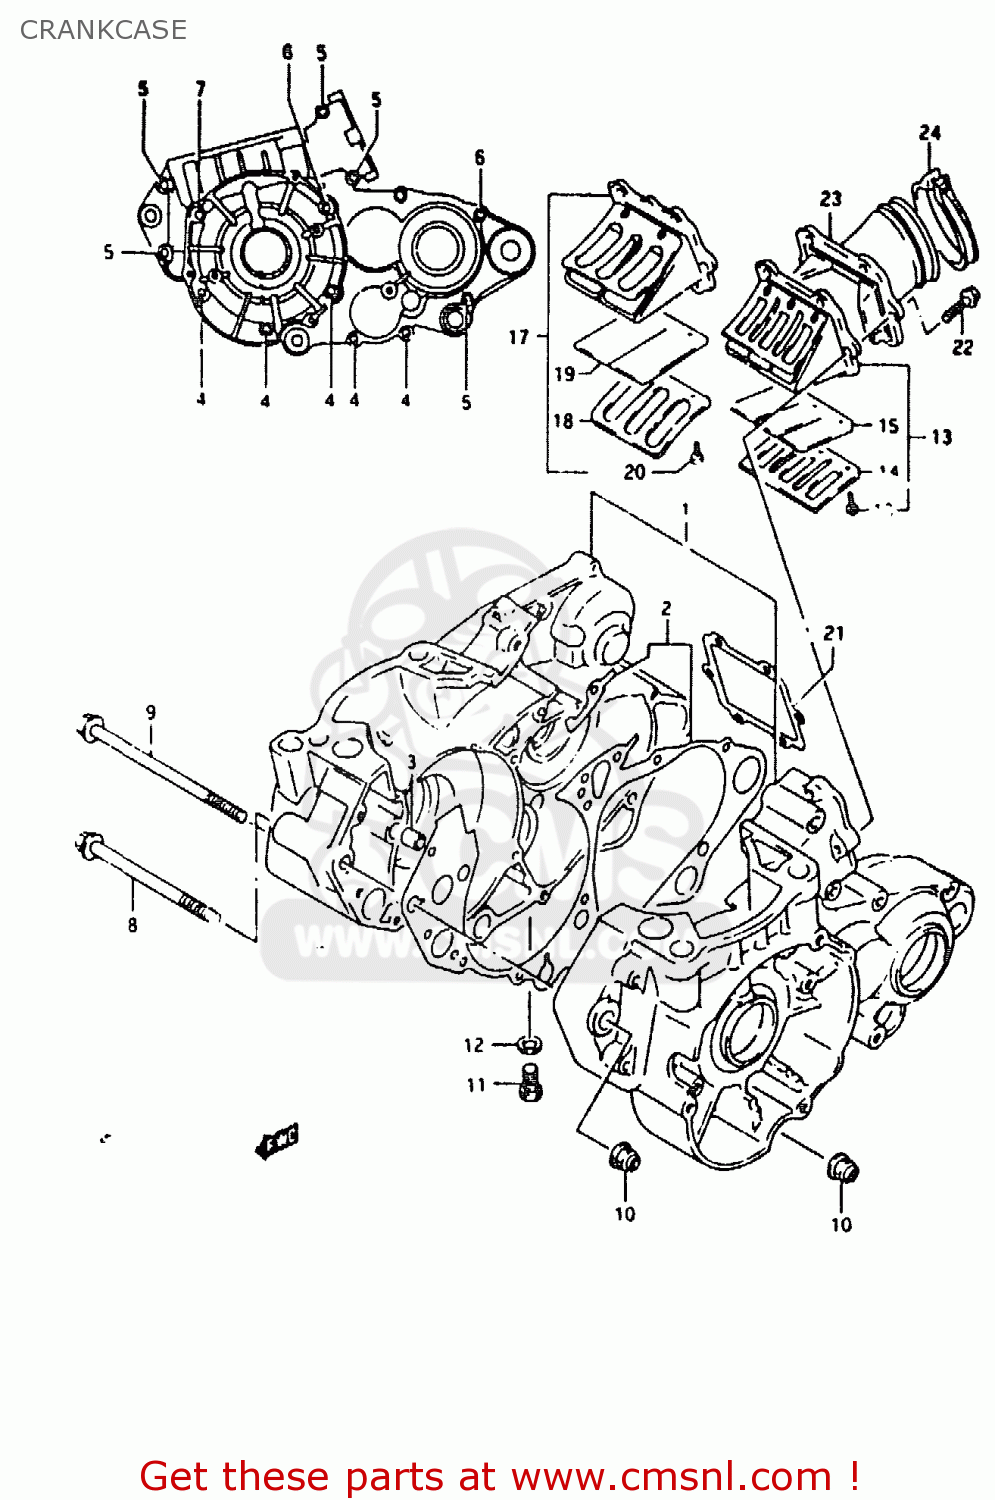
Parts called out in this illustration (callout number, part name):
1	CRANKCASE SET
2	GASKET,CRANKCASE (NAS)
3	PIN
4	BOLT
5	BOLT
6	BOLT
7	BOLT
8	BOLT
9	BOLT
10	NUT
11	BOLT
12	GASKET(8.2X14X1) (NAS)
13	VALVE ASSEMBLY,REED
14	STOPPER,REED VALVE
15	VALVE,REED
16	SCREW
17	VALVE ASSY,REED
18	STOPPER,REED VALVE
19	VALVE,REED
20	SCREW
21	GASKET,REED VALVE (NAS)
22	BOLT
23	PIPE,INTAKE
24	CLAMP
